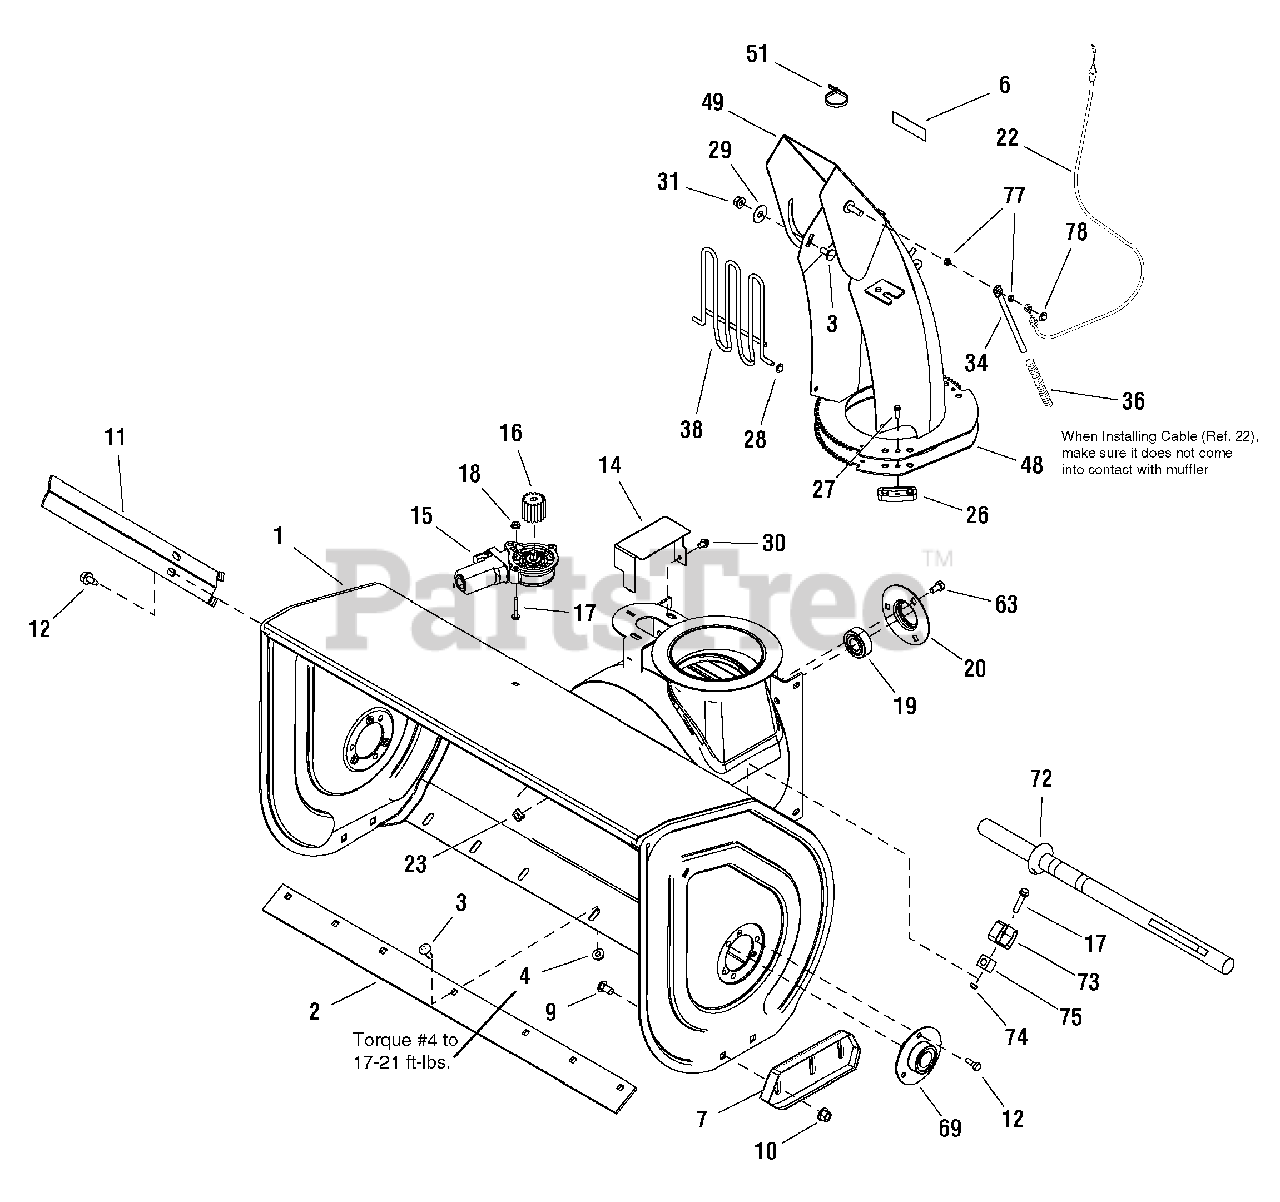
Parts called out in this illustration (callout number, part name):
1	HOUSING ASSEMBLY, 38"
2	BLADE, Scraper 38"
3	CARRIAGE BOLT, 5/16-18 x 3/4, G5
4	NUT, Hex Lock Flange, 5/16-18
6	DECAL, Red Strip
7	SKID SHOE
9	BOLT, Carriage, 3/8-16 X 1
10	NUT, Hex Flange 3/8-16 ESNA
11	CUTTER, Drift
12	SCREW, Hex Washer Head Taptite, 5/16-18 x 3/4
14	COVER, Gear 38"
15	MOTOR, Spout Rotator 38"
16	PINION, 1.417OD .296 Slot, 1-1/4 LG, 16T Powdered Metal
17	CAPSCREW, Hex Washer, #10 x 1-1/4
18	NUT, Hex Whiz Lock Flange, 10-24
19	BEARING, 3/4 ID x 1.78 OD x .61 LG Greased
20	RETAINER, Bearing
22	CABLE, Deflector Control
23	RETAINER, Nut, 5/16-18 .057/.092
26	HOLD DOWN, Chute Black Nylon
27	SCREW, Hex Washer Head Plastite, 10-14 x 5/8
28	NUT, Push Pal, 1/4 DIA Stud Capped
29	WASHER, Nylon, .388 x 1.12 x .03
30	SCREW, Hex Washer Head Taptite, 1/4-20 x 3/8
31	NUT, Hex Flange, 5/16-18 ESNA
34	ROD, 5/16 DIA 5.88 LG
36	SPRING, Compression
38	GUARD & SUPPORT ASSEMBLY, Chute
48	GEAR, Chute, 10 OD x 6.65 ID x .105 TH
49	CHUTE ASSEMBLY, 38"
51	TIE, Self Locking, .184 WD 7.31 LG
63	SCREW, Hex Whiz Lock Flange, 5/16-18 x 3/4
69	BEARING, Ball, 1.002 ID 2.049 OD 1.09 LG
72	STICK, Cleanout w/Brush, Snow
73	CLIP, Retainer
74	NUT, Hex Lock, 10-24 with Nylon Insert
75	BLOCK, Universal Pivot
77	SPACER
78	NUT, Push
